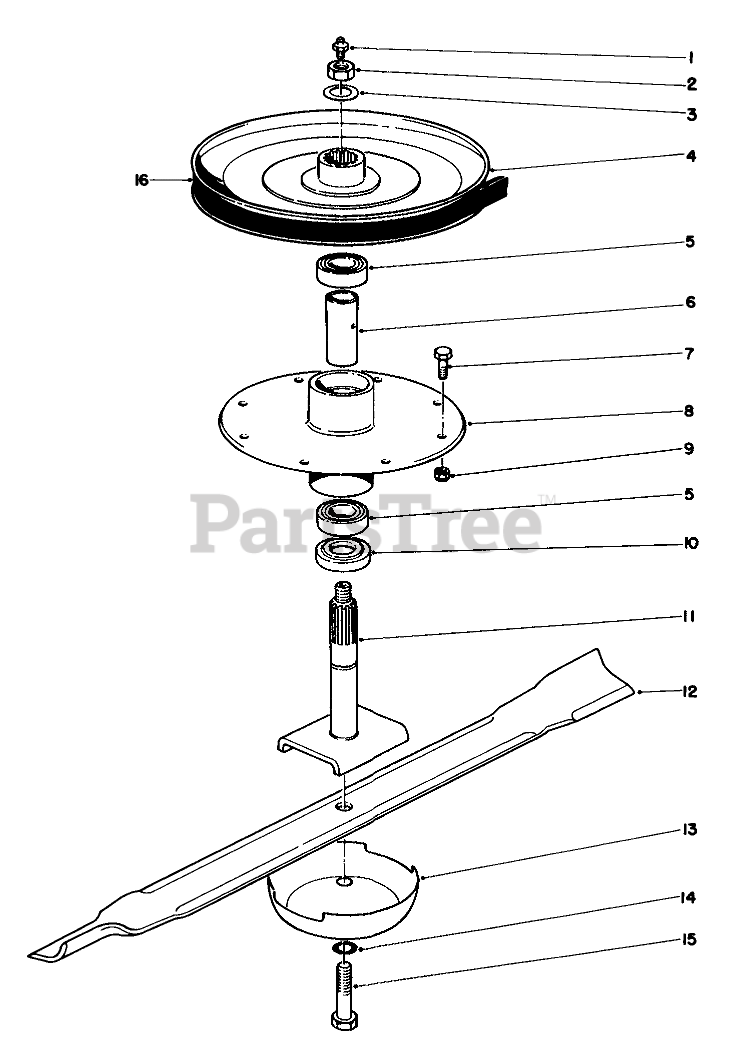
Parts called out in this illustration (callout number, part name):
1	FITTING-GREASE
2	NUT-LOCK, CONE
3	WASHER-FLAT
4	PULLEY ASM
5	BEARING-BALL
6	SPACER-BEARING
7	SCREW-HH
8	HOUSING-SPINDLE
9	NUT-LOCK, NI
10	SPACER
11	Shaft-Spindle
12	Blade
13	Cup
14	Washer-Lock
15	SCREW-BLADE
16	V-BELT
